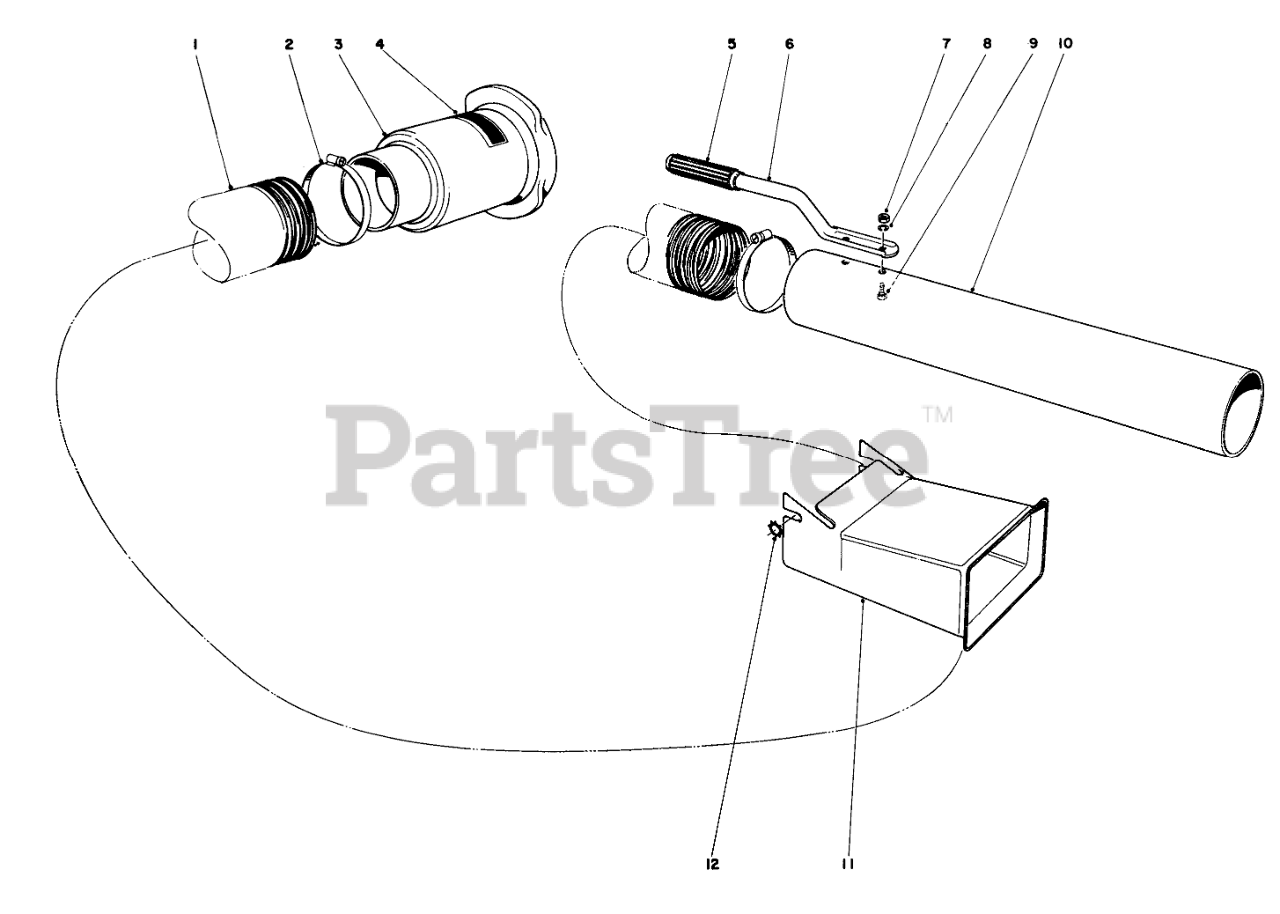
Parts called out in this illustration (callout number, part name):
2	Clamp
3	Hose Adaptor
4	Decal
6	Handle
7	NUT-HEX
8	WASHER-LOCK
9	Screw
10	Nozzle
11	Bag Adaptor
12	Lockwasher
